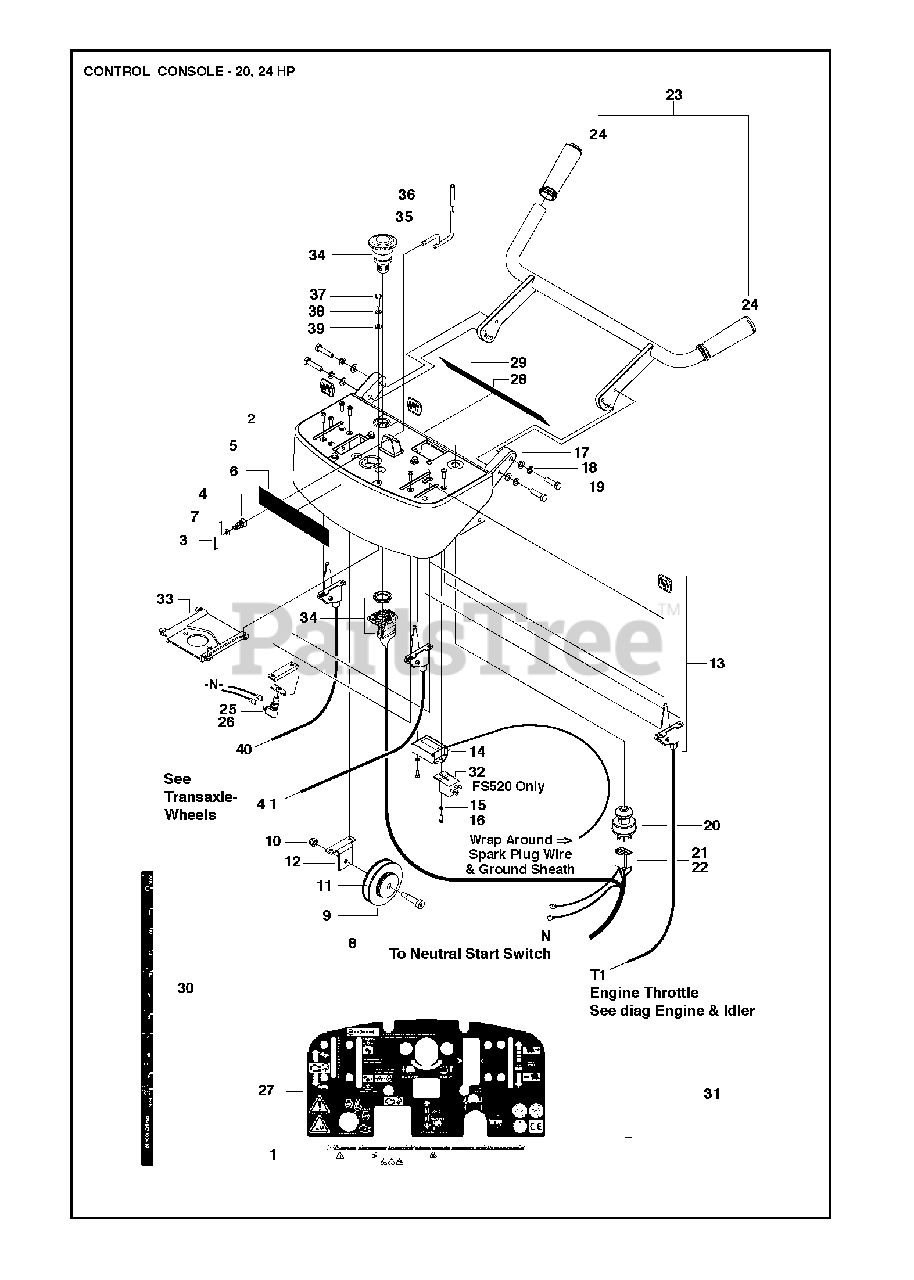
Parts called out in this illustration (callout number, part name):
15	SPRING WASHER 4.1X7.1
17	WASHER
18	SPRING WASHER
